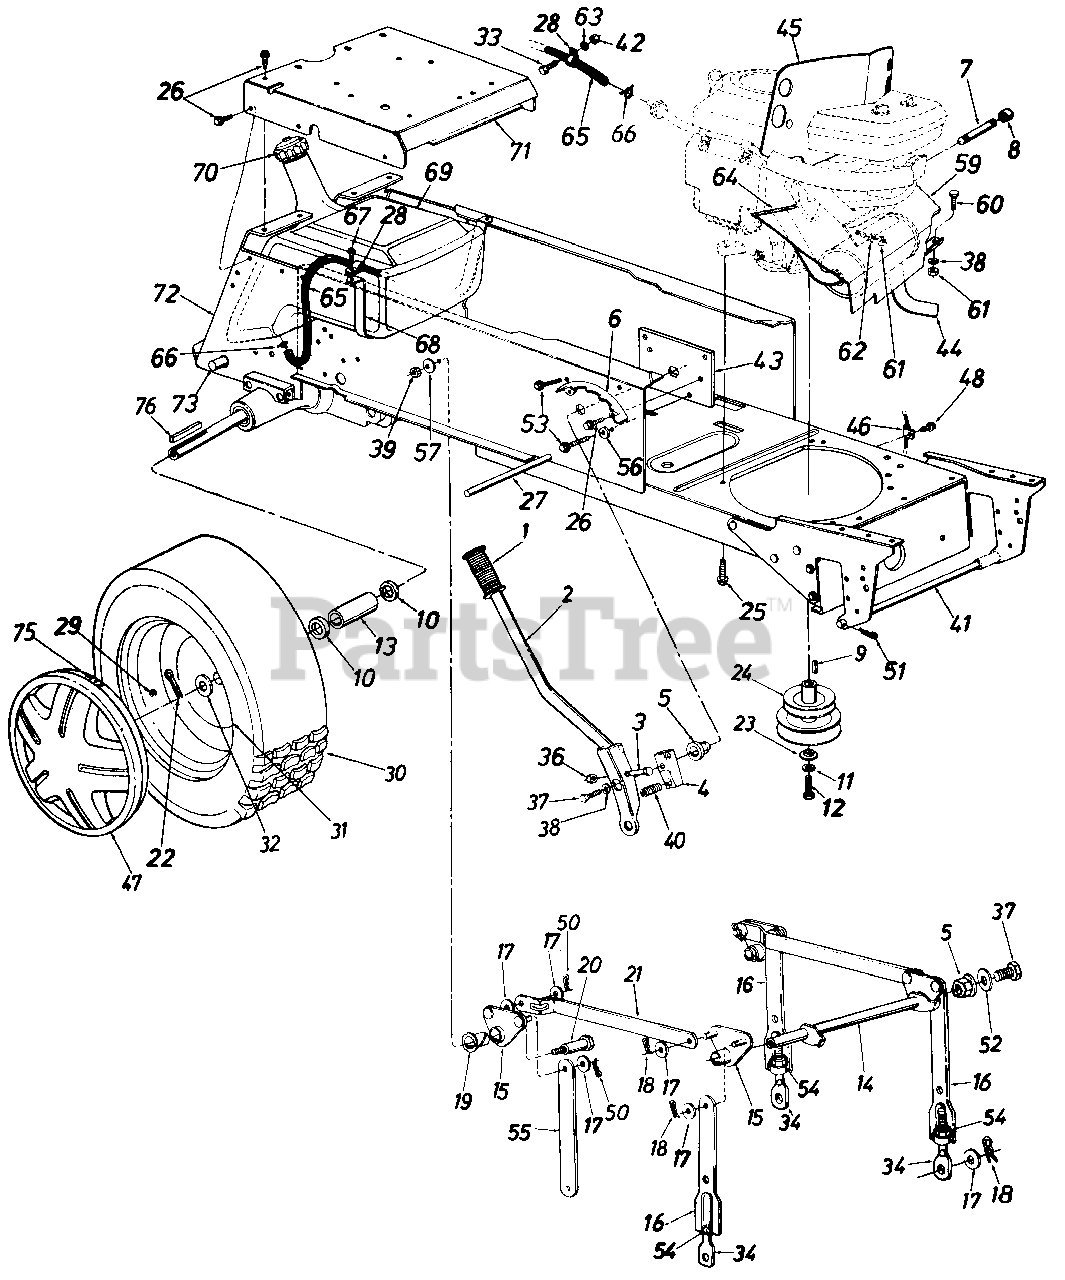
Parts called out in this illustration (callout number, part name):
1	Grip
2	Lift Handle Ass'y.
3	Hex Bolt 5/16-18 x 1.5"'Lg.
4	Lift Shaft Drive
5	Plastic Hex Brg. 5/8 I.D.
8	Pipe Cap 3/8-18 Npt.
9	Sq. Key 1/4" x 1/4" x 1 .50 Lg.
10	Fl-Wash. 1.03" l.D. x 1.62" O.D.
11	L-Wash. 7/16" I.D.
12	Hex Scr. 7/16-20 x 1 50" Lg.
13	Spacer 1,on l.D. x 1.25 O.D.
14	Lift Shaft Ass'y.
15	Lift Pivot Brkt. Ass'y.
17	Fl-Wash. 1/2" l.D. x 1.00" O.D. x .090"
18	Hairpin Cotter
19	Nyliner 5/8" l.D. x .88" Lg.
20	Shld. Bolt 5/8" Dia. x .96" Lg. 3/8-16
23	Flat Wash. ,44" l.D. x 1.25" O.D. x ,17n
24	Two-Step Engine Pulley
25	Hex Wash. Hd. Scr. 3/8-16 x 1.25" Lg.
26	Hex Thd. Rolling Scr. 5/16-18 x .75" Lg.
27	Running Board Rod
29	Air Valve
33	Hex Bolt 1/4-20 x .62" Lg.
34	Eye Bolt Adj. Link 1/2-13 Thd.
36	Hex Cent. L-Nut 5/16-18 Thd.
37	Hex Scr. 5/16-24 x .62" Lg t
38	L-Wash. 5/16" l.D.
39	Hex Top L-Nut 3/8-16 Thd.
40	Compression Spring
41	Deck Connecting Rod
42	Hex Nut 1/4-20 Thd.
45	Heat Shield
46	Mounting Clamp
48	Hex Wash. Hd. TT-Tap Scr. 1/4-20 x 5" Lg .
50	CoKer Pin .09 Dia. x 1.0" Lg.
51	Int. Cotter Pin
52	Flat Wash. 34" l.D. x 1.12" O.D. x 125"
53	Hex Wash. Hd. AB-Tap Scr. 5/124 x 5" Lg.
54	Hex Nut 1/2-13 Thd.
56	Fl-Wash..344" l.D.
57	Bell-Wash. .4" l.D. x 1.13" O.D.
59	Front Heat Shield
60	Hex Bolt 5/16-18 x .75" Lg.
61	Hex Nut 5/16-18 Thd.
62	L-Wash. 5/16" l.D.
63	L-Wash. 1/4" l.D.
64	Trim Strip 10" Lg.
65	Fuel Line 50" Lg.
67	Hex AB-Tap Scr. 1/4 x .62" Lg.
68	Fuel Tank Strap
69	Gas Tank
70	Gas Gauge
71	Seat Plate
75	Spring Clip
76	Sq. Key 1/4" x 3" Lg.
